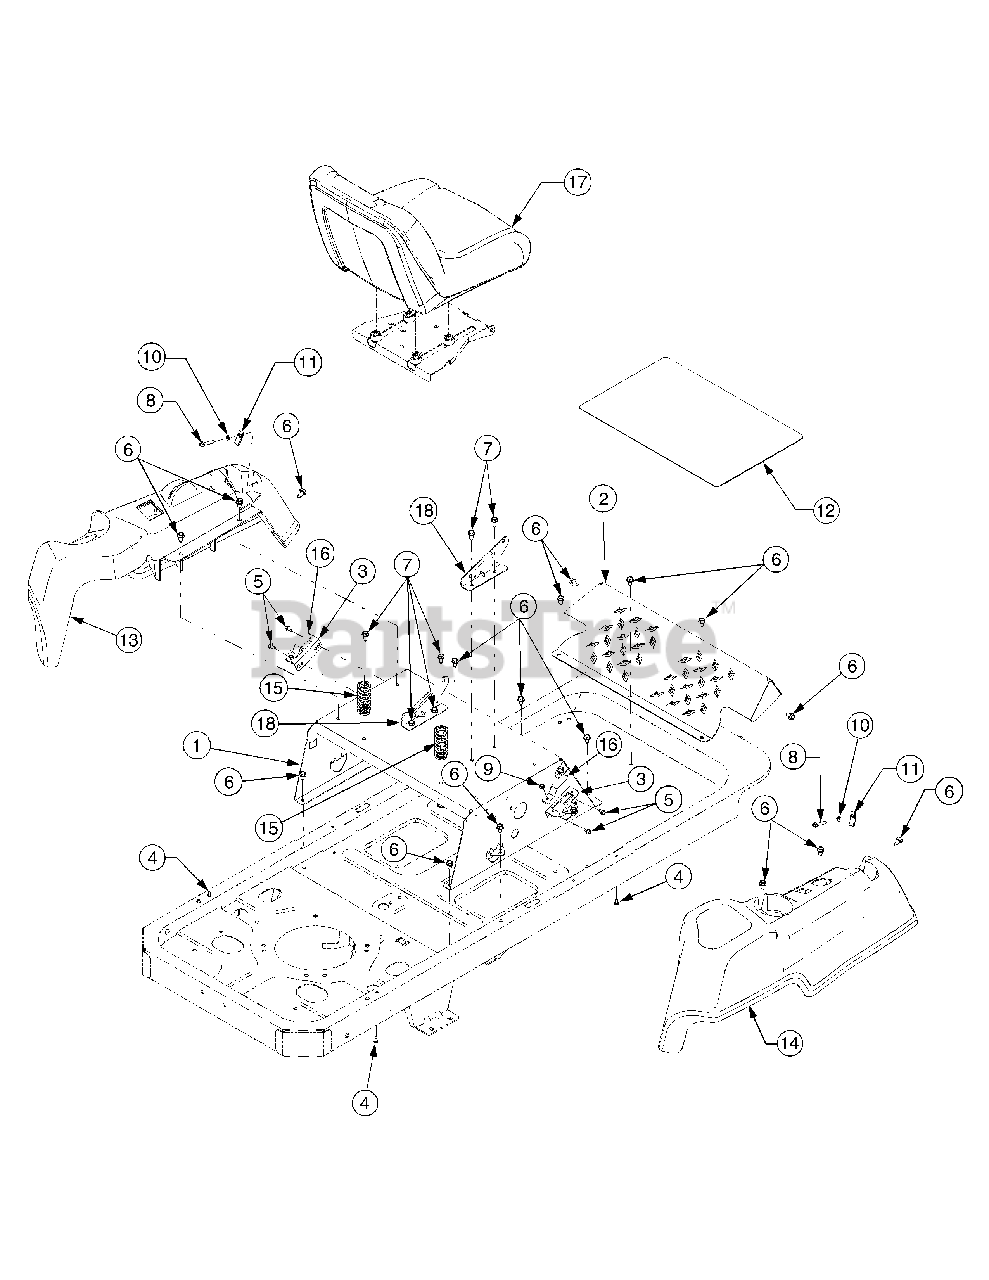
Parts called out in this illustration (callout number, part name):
4	Screw, Hex Wash. Hd Tapp #12-16 x .50
5	Screw, Hex Wash. Hd. Tapp. 1/4-20 x .5
6	Screw, Hex Wash. Hd. Tapp 5/16-18 x .625
7	Screw, Hex Wash. Hd. Tapp 5/16-12 x .75
8	Screw, Hex Wash. Hd. Tapp. 1/4-20 x 1.5
9	Screw, Hex Wash. Hd Tapp #10-16 x .375
10	Nut, Hex Jam, 1/4-20 GR2
11	Nut, U Type Speed, 1/4-20
12	Pad, Abrasive Foot Plate
13	Console, LH
14	Console, RH
15	Spring, Compression, 1.28 x 3.125
16	Spring, Switch Actuator
